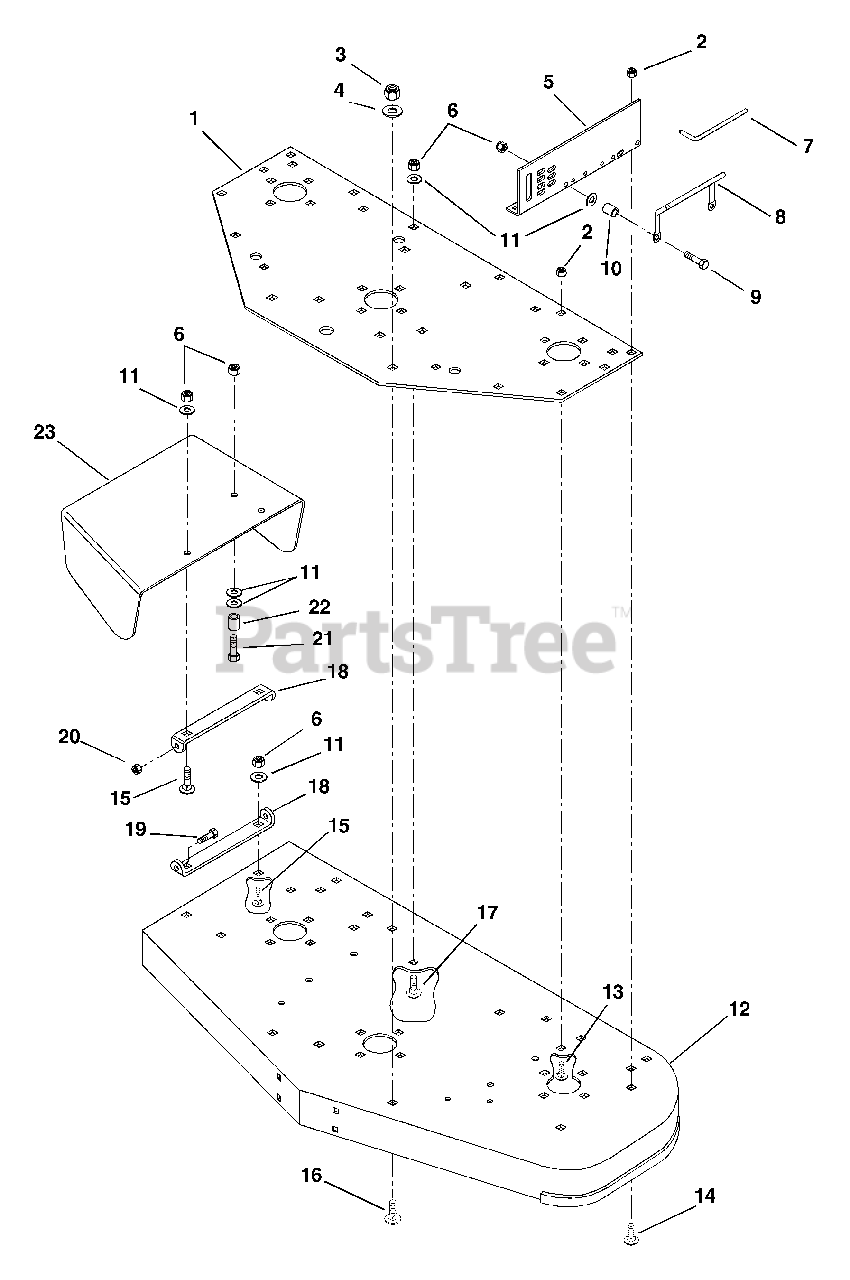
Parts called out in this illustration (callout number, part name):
1	Plate, Support
2	Nut-Locking-Nylon .31-18 w/ Insr Grade 2
3	Nut-Locking-Nylon .50-13 Grade 5
4	Washer-Flat-Steel .531 x 1.250 x .100
5	Bracket, Mower Side Support Left Hand
5	Bracket, Mower Side Support Right Hand
6	Nut-Locking-Nylon .38-16 w/ Insr Grade 2
7	Pin, Mower Locking
8	Handle
9	Bolt-Hex .38-16 x 1.75 Grade 5
10	Bushing
11	Washer-Flat-Steel .406 x .812 .065
12	Weldment, 50" Mower Fabricated
13	Bolt-Round Head Square Neck .31-18 x .62
14	Bolt-Round Head Square Neck .31-18 x 1.00
15	Bolt-Round Head Square Neck .38-16 x 1.00
16	Bolt-Round Head Square Neck .50-13 x 1.00
17	Bolt-Round Head Square Neck .38-16 x .75 Grade 1
18	Bracket, Chute
19	Bolt-Hex .25-20 x .88
20	Nut-Locking-Nylon .25-20 w/ Insr Grade 2
21	Bolt-Hex .38-16 x 1.50 Grade 5
22	Bushing-Sleeve .407 x .812 x .065
23	Shield, Safety Extension 50" Mower
